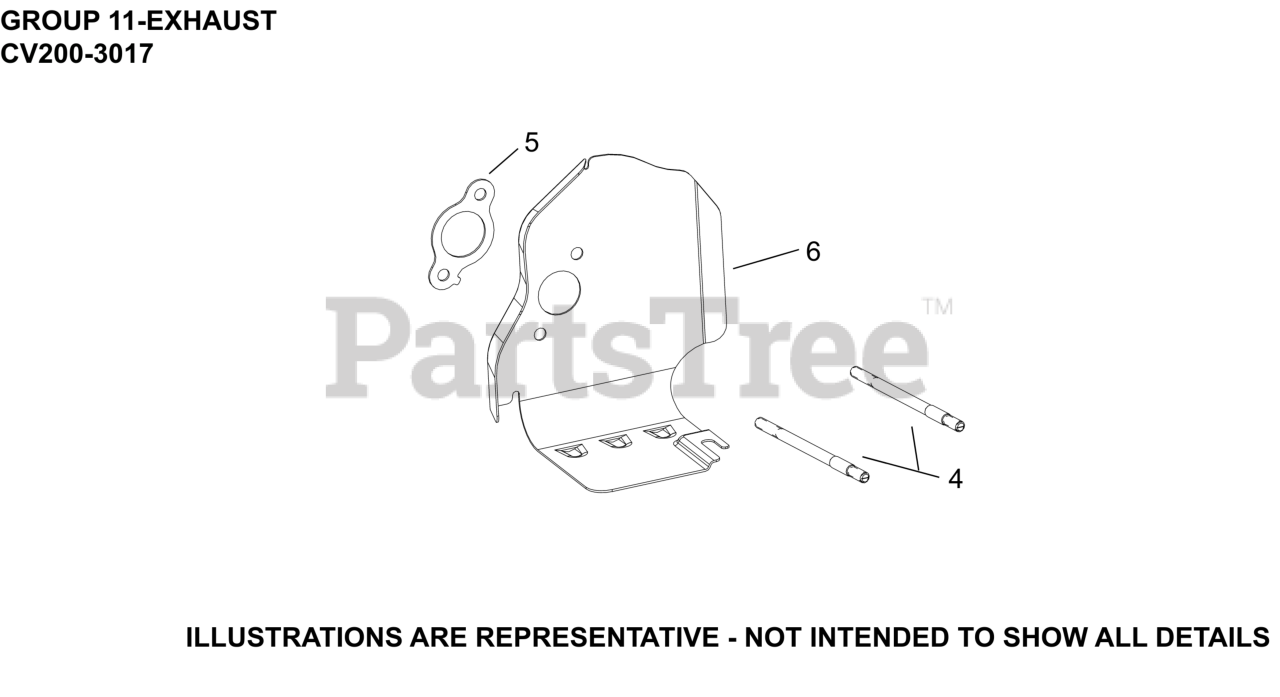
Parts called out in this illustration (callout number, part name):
4	STUD, EXHAUST (M6)
5	GASKET, MUFFLER (HEAT DEFLECTOR)
6	BAFFEL, BARREL
NI	KIT, MUFFLER
NI	GUARD, MUFFLER ASSEMBLY
NI	KIT, SPARK ARRESTER
NI	SCREW, CROSS RECESS PAN HEAD
